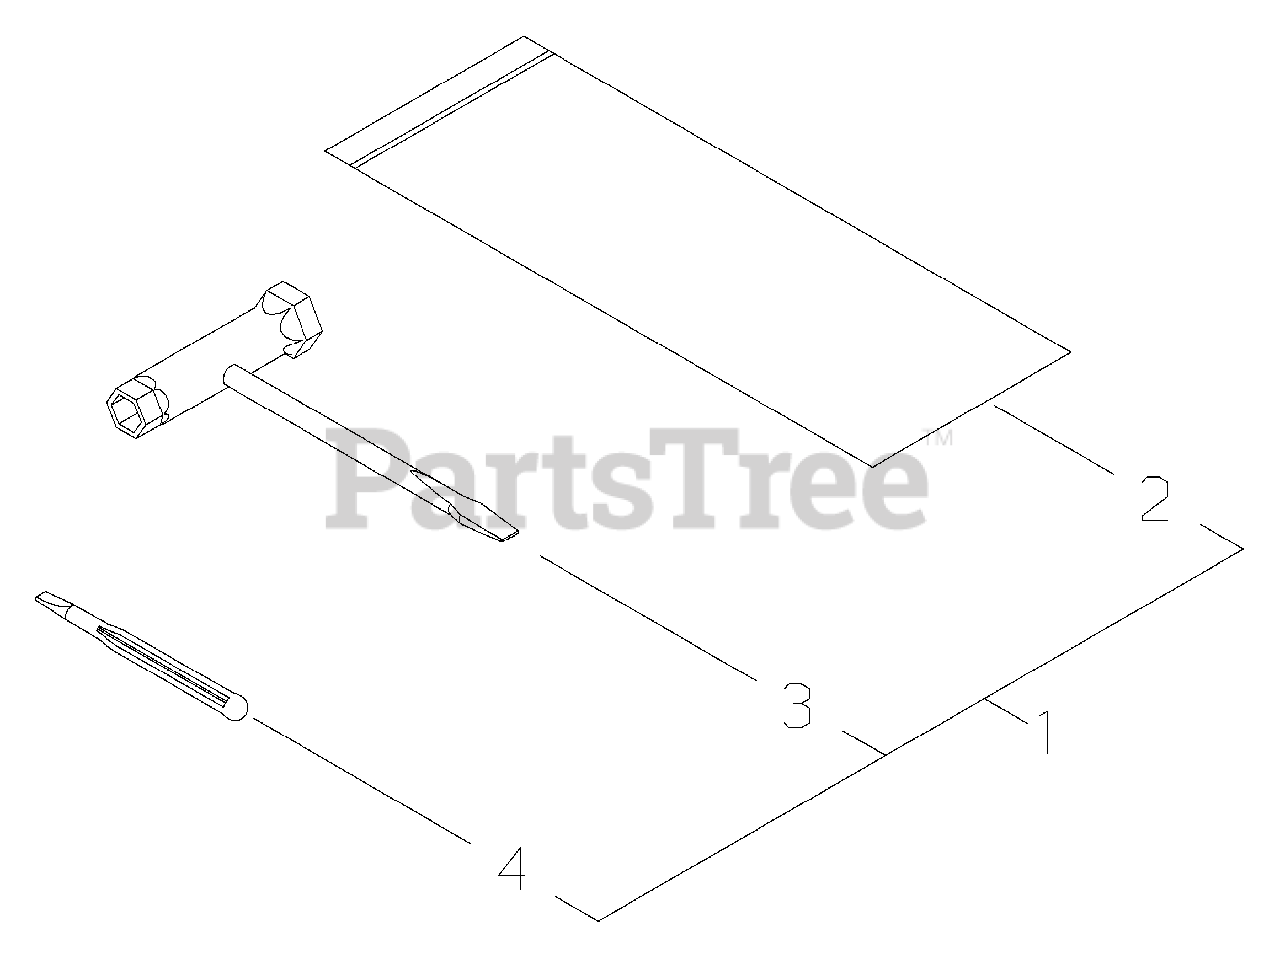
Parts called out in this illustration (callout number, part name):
1	TOOL KIT, SERVICE
2	BAG, TOOL
3	T-WRENCH 13×19 MM
4	SCREWDRIVER, PLASTIC
